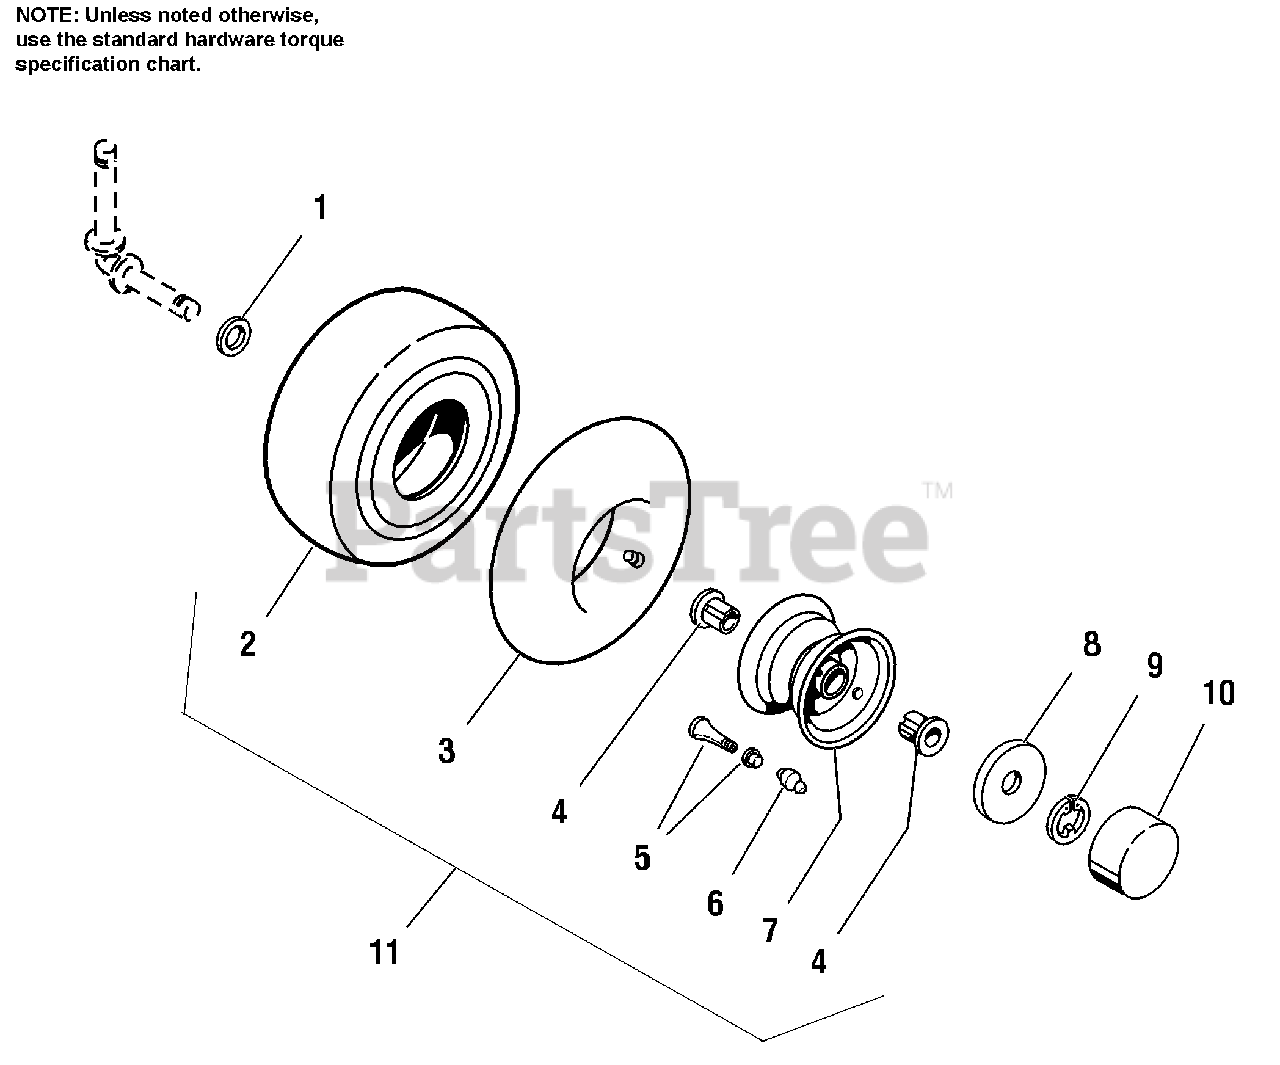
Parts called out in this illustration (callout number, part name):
1	WASHER, Special 3/4
2	TIRE, 15 x 6.00-6 (Dico)
3	TUBE, 4.10/3.50-6
4	BEARING
5	VALVE STEM & CAP
6	GREASE FITTING
7	WHEEL ASSY., Metallic Gray
8	RETAINER, Cap, Hub
9	RING, Retaining
11	WHEEL & TIRE ASSY. 15 x 6.00-6, Metallic Gray
